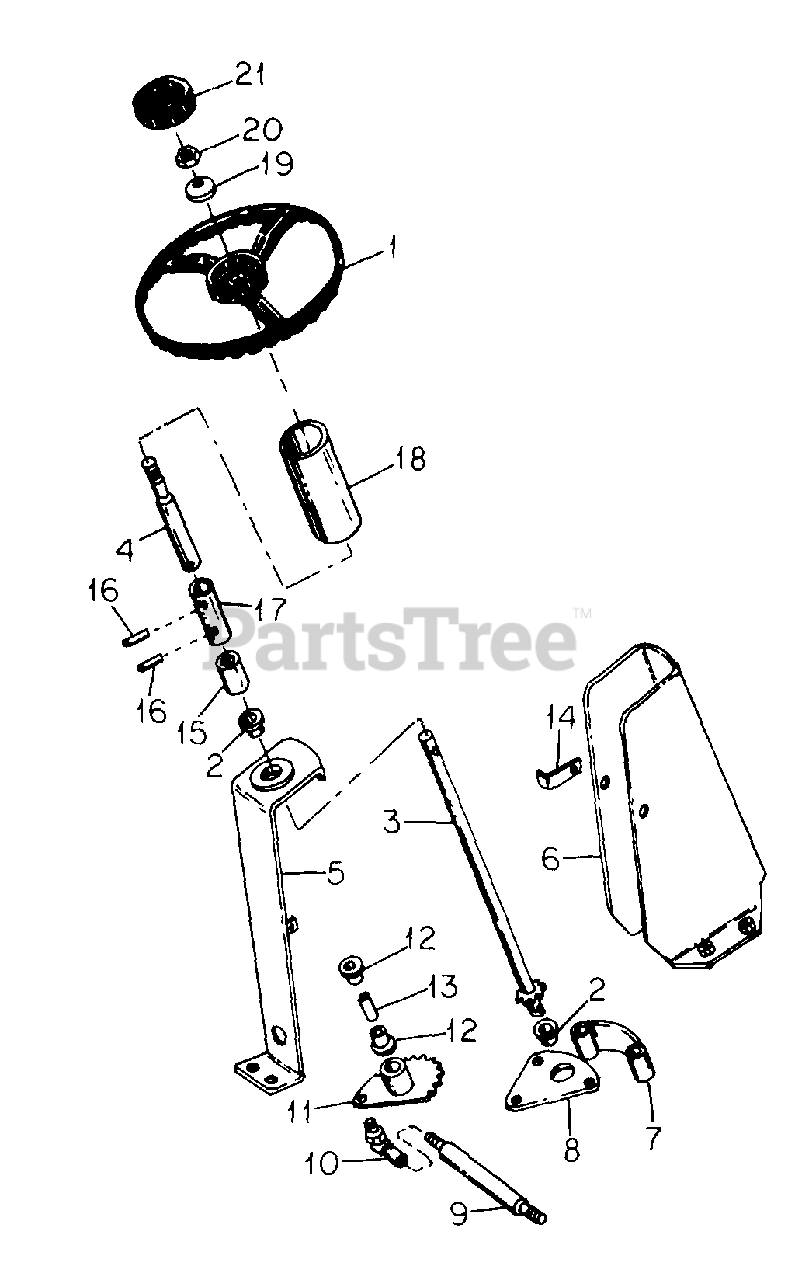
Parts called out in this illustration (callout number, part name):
1	WHEEL, STEERING
2	BEARING, STEERING SHAFT
3	SHAFT ASSY, LOWER STEERING
4	SHAFT, UPPER STEERING
5	SUPPORT ASSY, STEERING
6	SHROUD ASSY, STEERING SUPPORT
7	COVER, FRT STEERING GEAR
8	COVER ASSY, STEERING GEAR
9	STUD. DRAG LINK ROD
10	JOINT, 3/8 C-Z TYPE G BALL
11	GEAR ASSY, STEERING DRAG LINK
12	BEARING, STEERING GEAR
13	BUSHING, STEERING GEAR DRAG LINK
15	SPACER, STEERING SHAFT
16	PIN, 1/4 X 1-3/8 MED PLN CLD SPR
17	BUSHING, SHAFT SLEEVE
18	SPACER, STEERING TUBE
19	WASHER, BELLEVILLE
20	NUT, 5/16 CAD P/T LOCK TYPE 5
21	CAP, STEERING WHEEL
